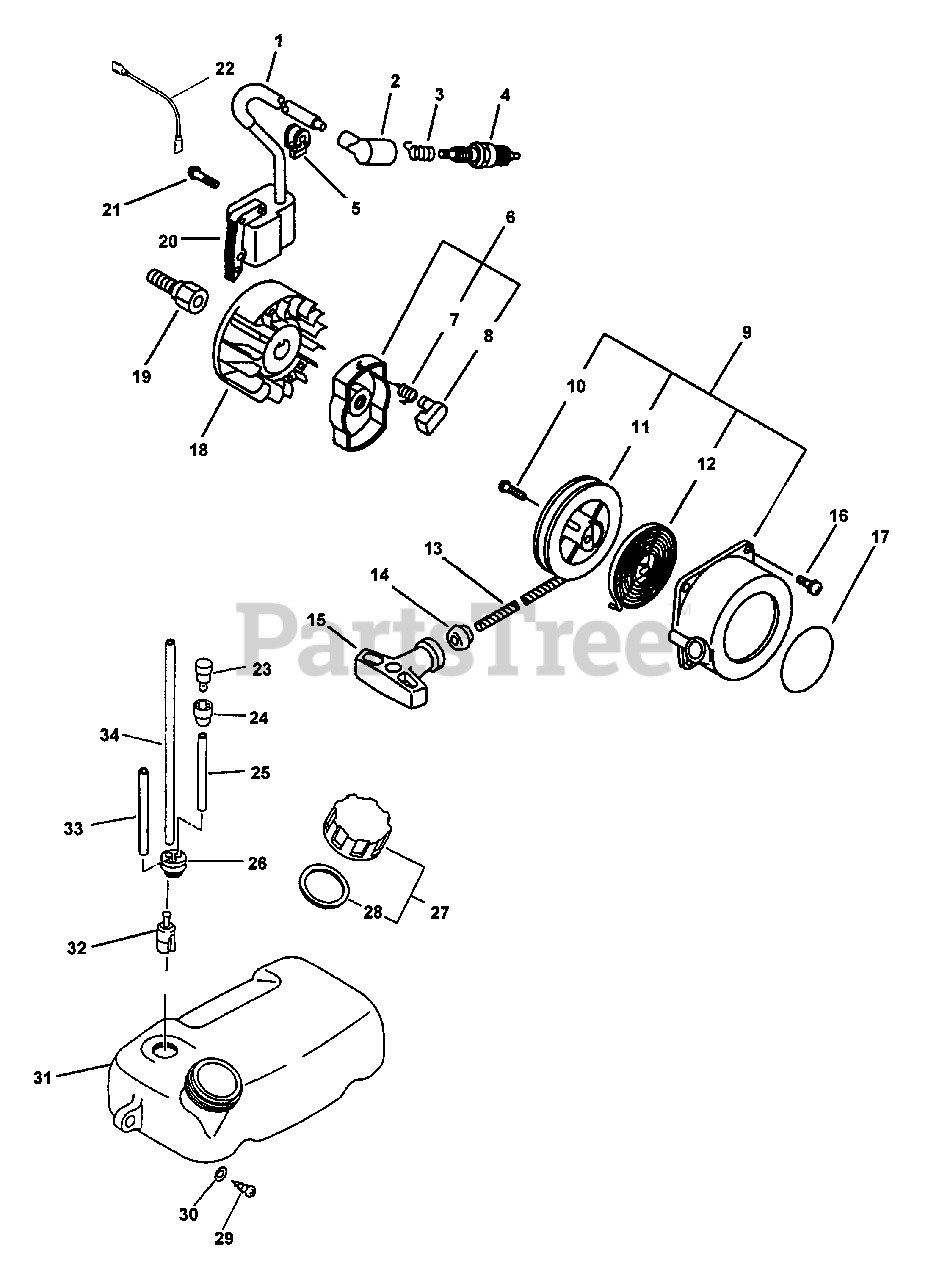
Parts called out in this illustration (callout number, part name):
2	CAP, SPARK PLUG
3	TERMINAL, SPARK PLUG
4	SPARK PLUG - BPM-7Y
6	PAWL ASSY, STARTER
7	SPRING, RETURN
8	PAWL, STARTER - BLACK
9	STARTER ASSY
10	SCREW
11	REEL, ROPE
12	SPRING, RECOIL
13	BULK STARTER ROPE - Ø 4.0 MM×61 M
14	GUIDE, ROPE
15	GRIP, STARTER
16	SCREW 4×22
17	LABEL, ECHO
18	FLYWHEEL
19	HUB, FAN
20	COIL, IGNITION
21	SCREW 4×22
22	LEAD - GROUND
23	VENT ASSY
24	HOLDER, VENT
25	PIPE, FUEL 3×5×90 BLACK
26	GROMMET, FUEL
27	CAP ASSY, FUEL
28	GASKET, FUEL CAP
29	SCREW, TAPPING 5×20
30	WASHER 5.5×12×0.8
31	TANK, FUEL
32	FILTER, FUEL
33	PIPE, FUEL RETURN 3×6×110
34	PIPE, FUEL 3×5×210 BLACK
